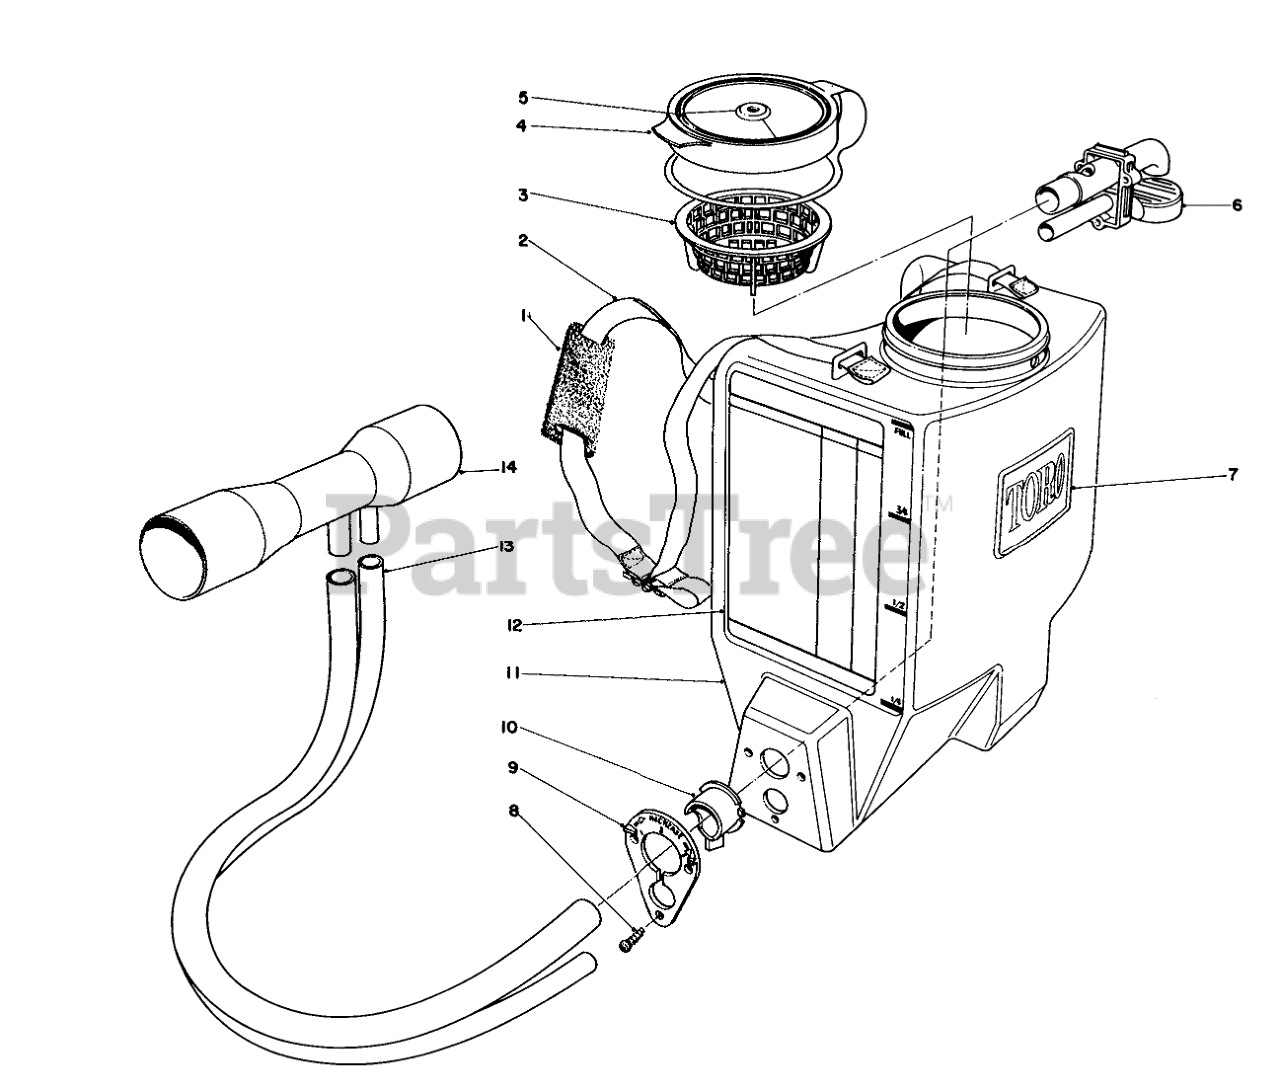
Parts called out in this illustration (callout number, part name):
1	SHOULDER PAD
2	Shoulder Strap
3	Strainer
5	CAUTION LABEL
6	PICKUP ASM MIXER
7	Decal-Toro
8	Screw
9	Bezel
10	Valve Delivery
11	CONTAINER
12	Label-Application
13	Tubing 2 Cell
14	ENTURI
